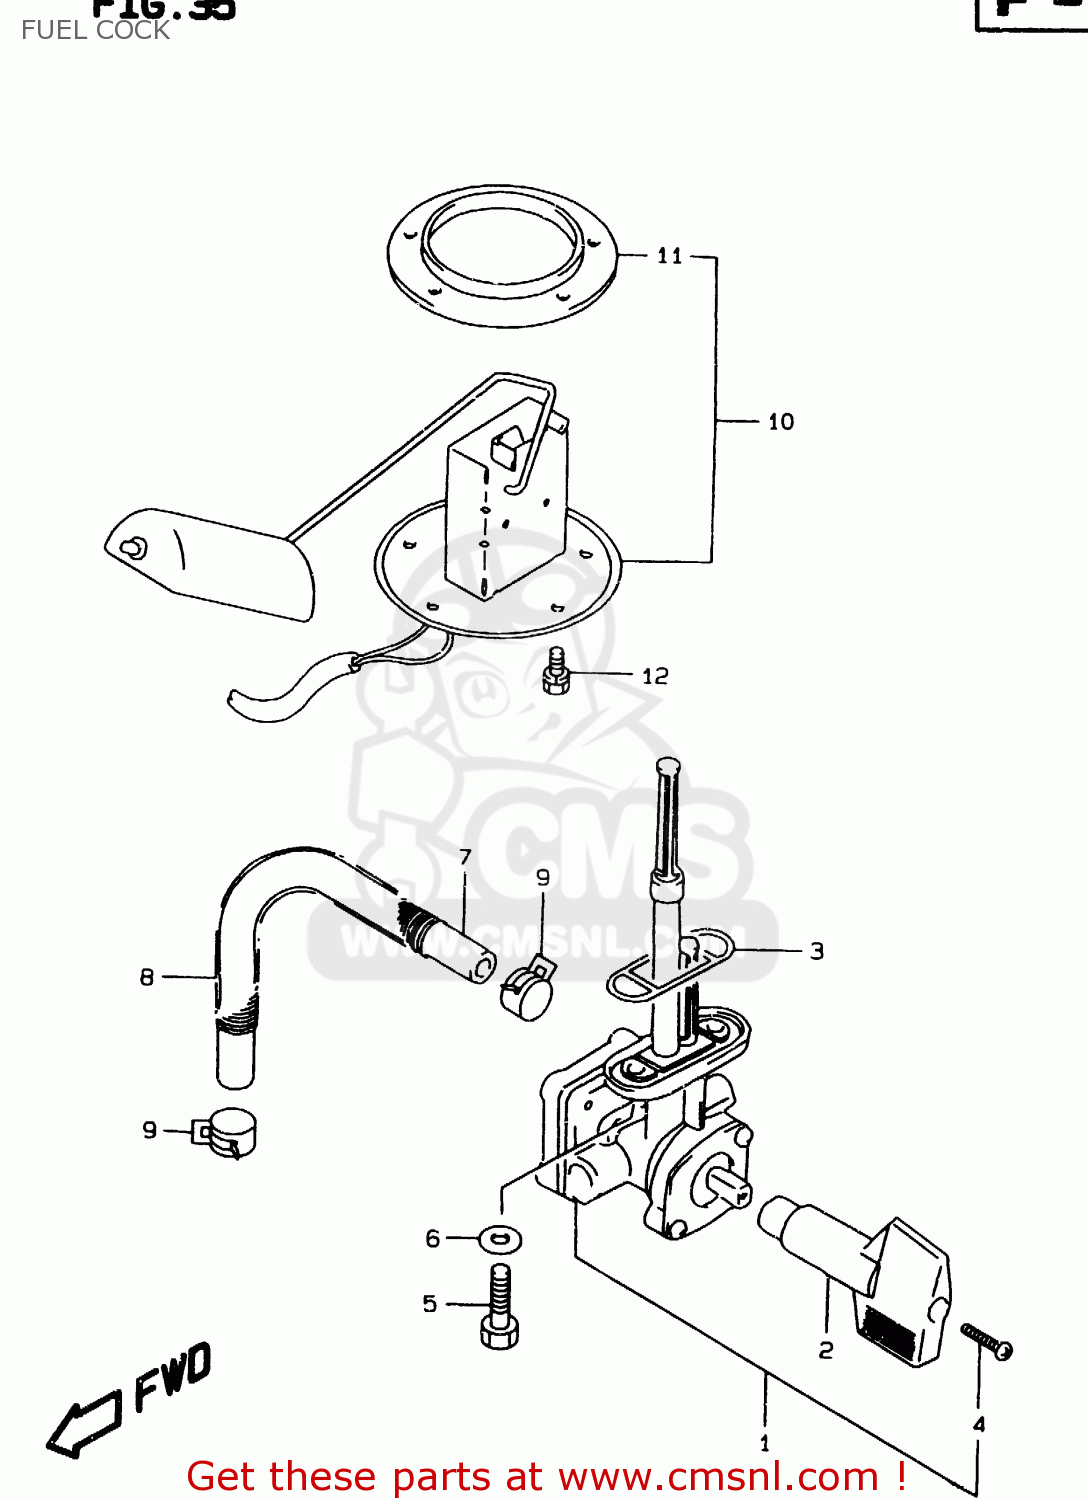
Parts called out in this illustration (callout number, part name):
1	COCK ASSEMBLY,FUEL
2	LEVER,FUEL COCK
3	GASKET,JOINT (NAS)
4	SCREW
5	BOLT(6X20)
6	GASKET(6.4X11.5X0.8) (NAS)
7	HOSE(7X12X600)
8	SPRING
9	CLIP
10	GAUGE ASSEMBLY,FUEL LEVEL
11	GASKET,FUEL LEVEL GAUGE (NAS)
12	BOLT 5X10
